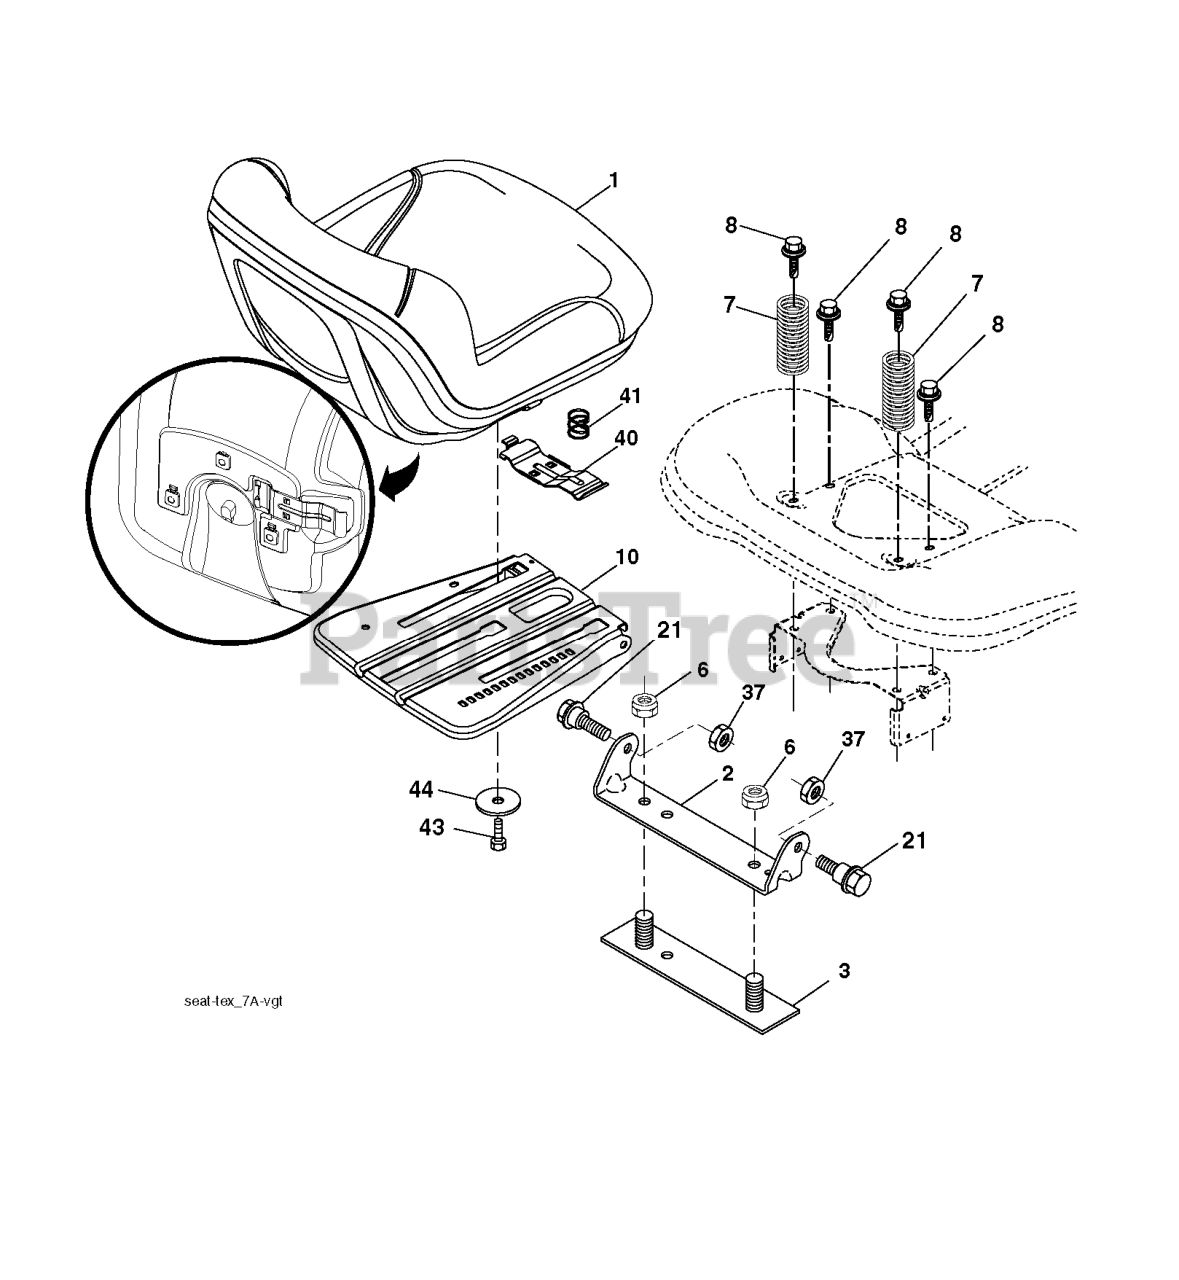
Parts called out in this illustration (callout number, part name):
1	SEAT - GREY
2	BRKT.PIVOT.FENDER
3	STRAP
6	NUT
7	SPRING COMPRESSION
8	BOLT.5/16-18UNCX3/4 W/SEMS.BLK
10	PAN.ASM.SEAT.3PT
21	BOLT.SHOULDER.5/16-18
37	NUT.71038.31-18.HEX.NYLOCK
40	HANDLE.SLIDE.SEAT.TEX.BLACK
41	SPRING.LATCH.SEAT.TEX
44	WASHER 13/32 X 2-3/8 X 12GA
